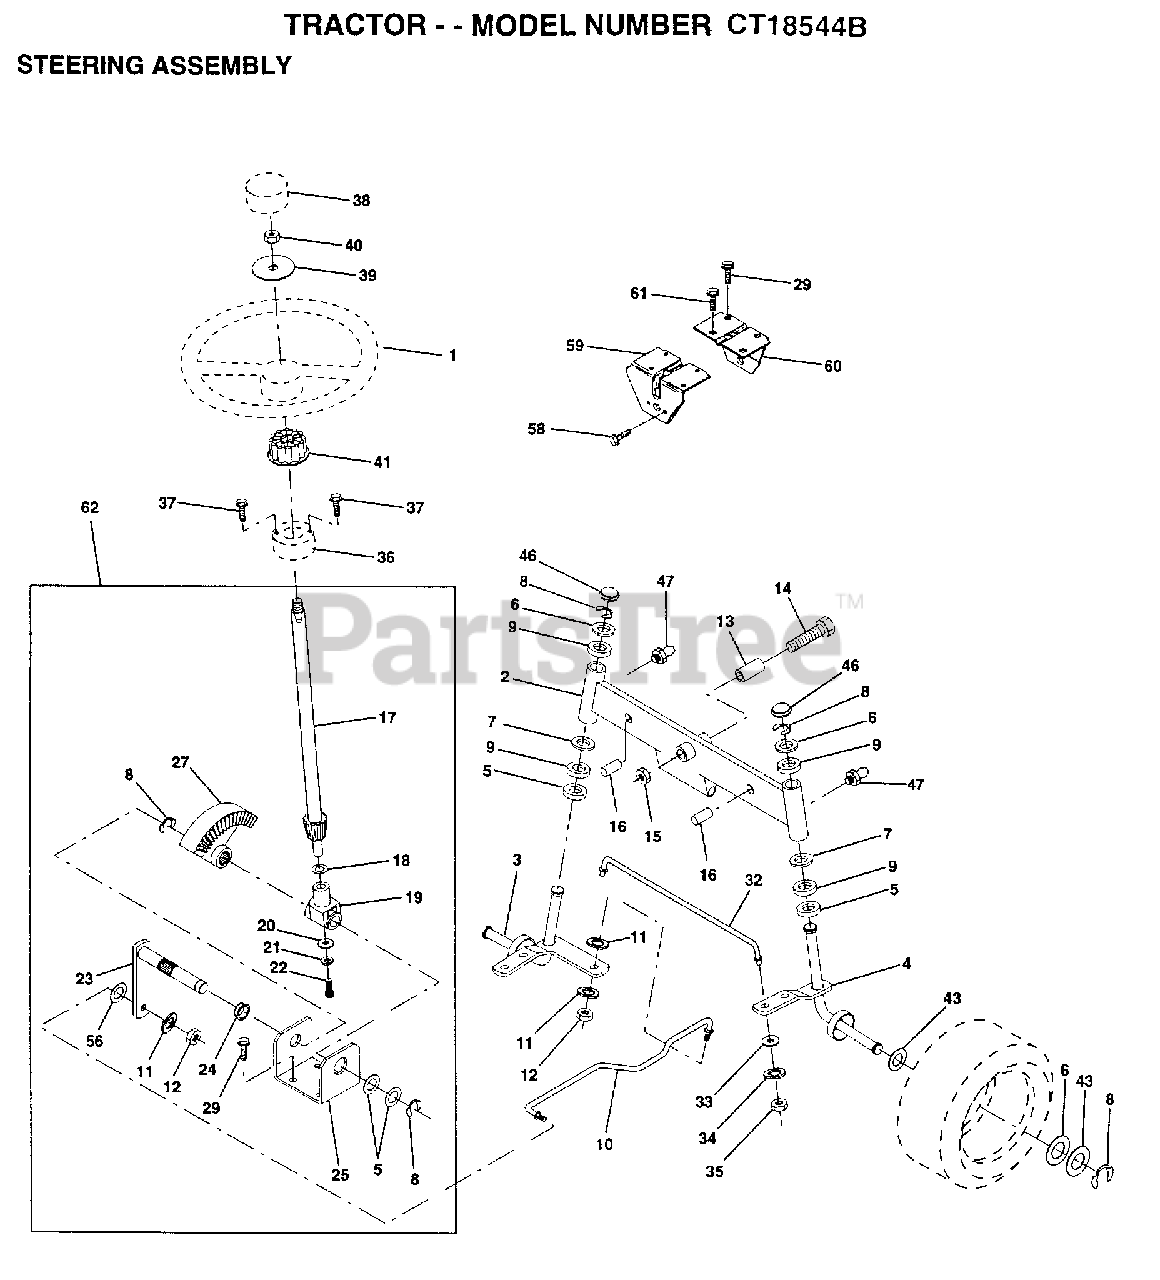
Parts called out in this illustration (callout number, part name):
1	WHEEL STR AYP BLK
2	AXLE ASM FRONT
5	WASHER .T
6	WASHER
7	WASHER
8	RING
9	COL. SRTG. BEAR.
11	LOCKWASHER
13	BEARING
14	BOLT LT
15	"NUT-LOC,FLANGE LT"
16	AXLE PIN
18	THRUST WASHER
19	SUPPORT.SHAFT
21	LOCKWASHER
22	SCREW.SCKTHD.CAP
24	NYLINER T
25	"BRKT,STEERING"
27	GEAR SECTOR
29	SCREW
32	TIE ROD
33	WASHER M
34	LOCKWASHER
35	NUT.LOCK.5/16-24
36	BUSHING.STRG.3/4
38	CAP STEER AYP
39	WASHER
40	GRIPCO NUT
41	ADAPTER LT
43	WASHER
46	CAP
47	ZERK M
56	WASHER
58	SCREW LT
59	SUPPORT-SADDL T
60	SUPPORT.SADDLE.FT
61	"SCREW-TT,10-32 FL"
62	KIT.STEER.20.31
